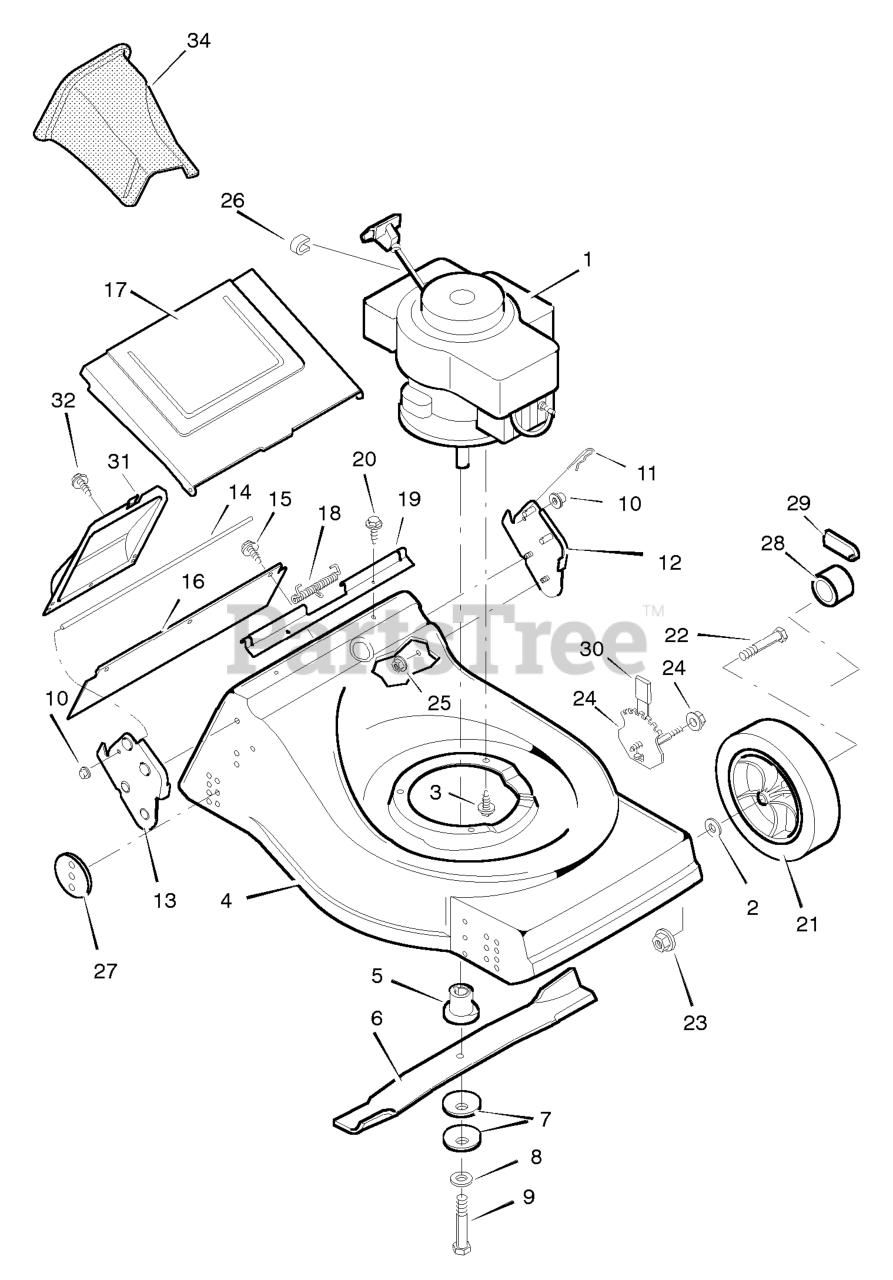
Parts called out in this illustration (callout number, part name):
1	Engine *
2	Washer
3	Bolt, Engine
4	Housing
5	Adapter, Blade
7	Washer, Belleville
9	Bolt, Hex
10	Push- On Cap
11	Pin, Hair
12	Bracket, Left Handle
13	Bracket, Right Handle
14	Rod, Door Pivot
16	Deflector, Rear
17	Door, Rear
18	Spring, Torsion
19	Spacer, Door
21	Wheel and Tire *
22	Bolt, Axle
23	Nut, Flange
24	Adjuster, Height
25	Nut, Flange
26	Stop, Rope
28	Hub Cap
29	Hub Cap
31	Cover, Transmission
34	Plug, Mulcher
